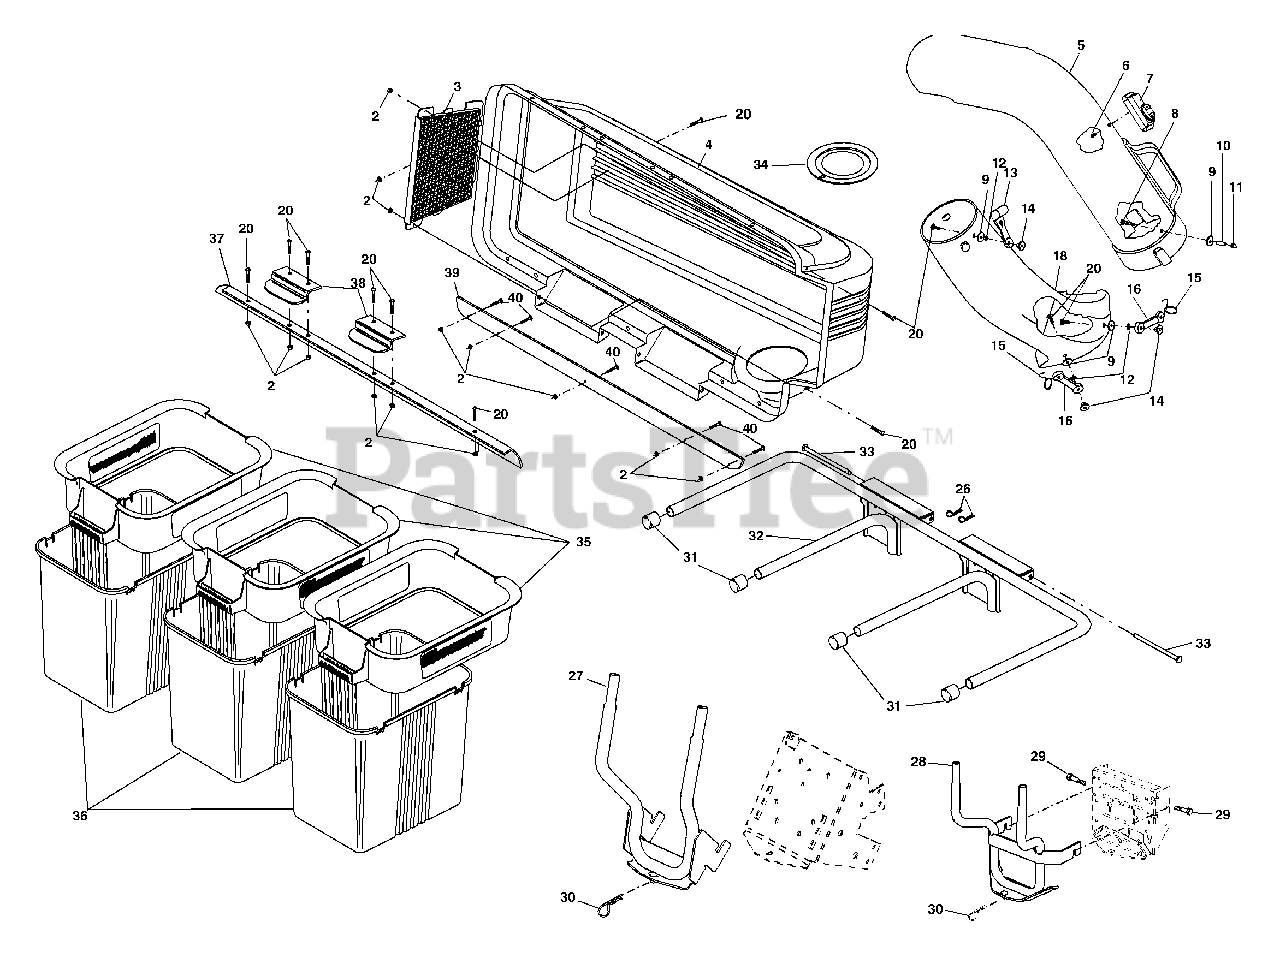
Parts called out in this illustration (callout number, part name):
2	Nut, Crownlock #10-24
3	Screen, Cover
4	Cover Assembly
6	Screw, Special #10-14x1/2
7	Dump Bag Indicator
8	Screw, #10-24 x 1-1/8
9	Washer 3/16x3/4x16 Ga.
10	Spacer, Split
11	Nut, Acorn #10-24
14	Nut, Weld
15	Latch, Hook
16	Rubber, Latch
20	Screw #10-24 x 5/8
26	Spring, Retainer
27	Support Assembly - GT
28	Support Assembly - LT
29	Shoulder Bolt,Self Tapping
30	Spring, Retainer
31	Plug, Tubing End
32	Bagger, Frame
33	Pin, Hinge
34	Gasket, Cover
35	Container, Top
36	Container, Bottom
38	Latch Handle, Cover
39	Strip, Reinforcement
40	Screw #10-24 x 1/2
